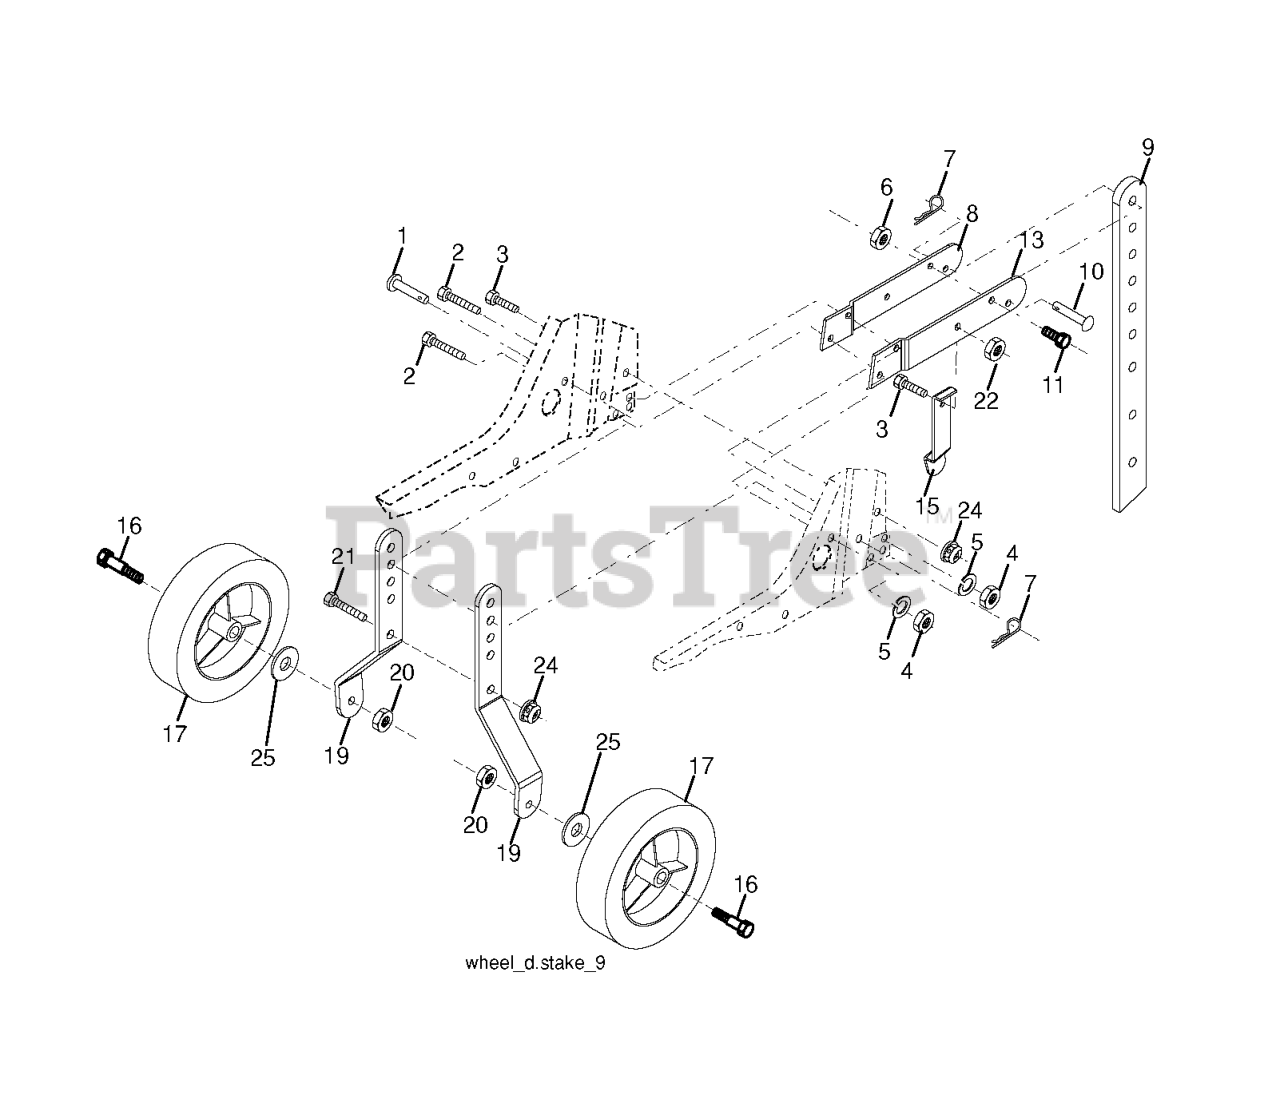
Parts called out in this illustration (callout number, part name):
1	PIN
2	BOLT
3	BOLT
5	WASHER.LOCK.HVY.HLCL.SPR.5/16
6	NUT
7	SPRING TI
8	SUPPORT.STAKE.RH.BLK(2 2MC)
9	RP STAKE.DEPTH.13.25.W/9HOLES
10	REPL BY 532 00 49-29
11	BOLT
13	REPL BY 532 14 92-09
15	REPL BY 532 12 47-24
16	BOLT.SHOULDER
17	WHEEL.8X1.75.STORM.GREY
19	RP.BRACKET.WHEEL.BLACK
21	BOLT RB
22	NUT.71038.31-18.HEX.NYLOCK
24	LOCKNUT-FLANGE 5/16-18
25	Washer 1 17/32 X 7/8 X 16 Ga
